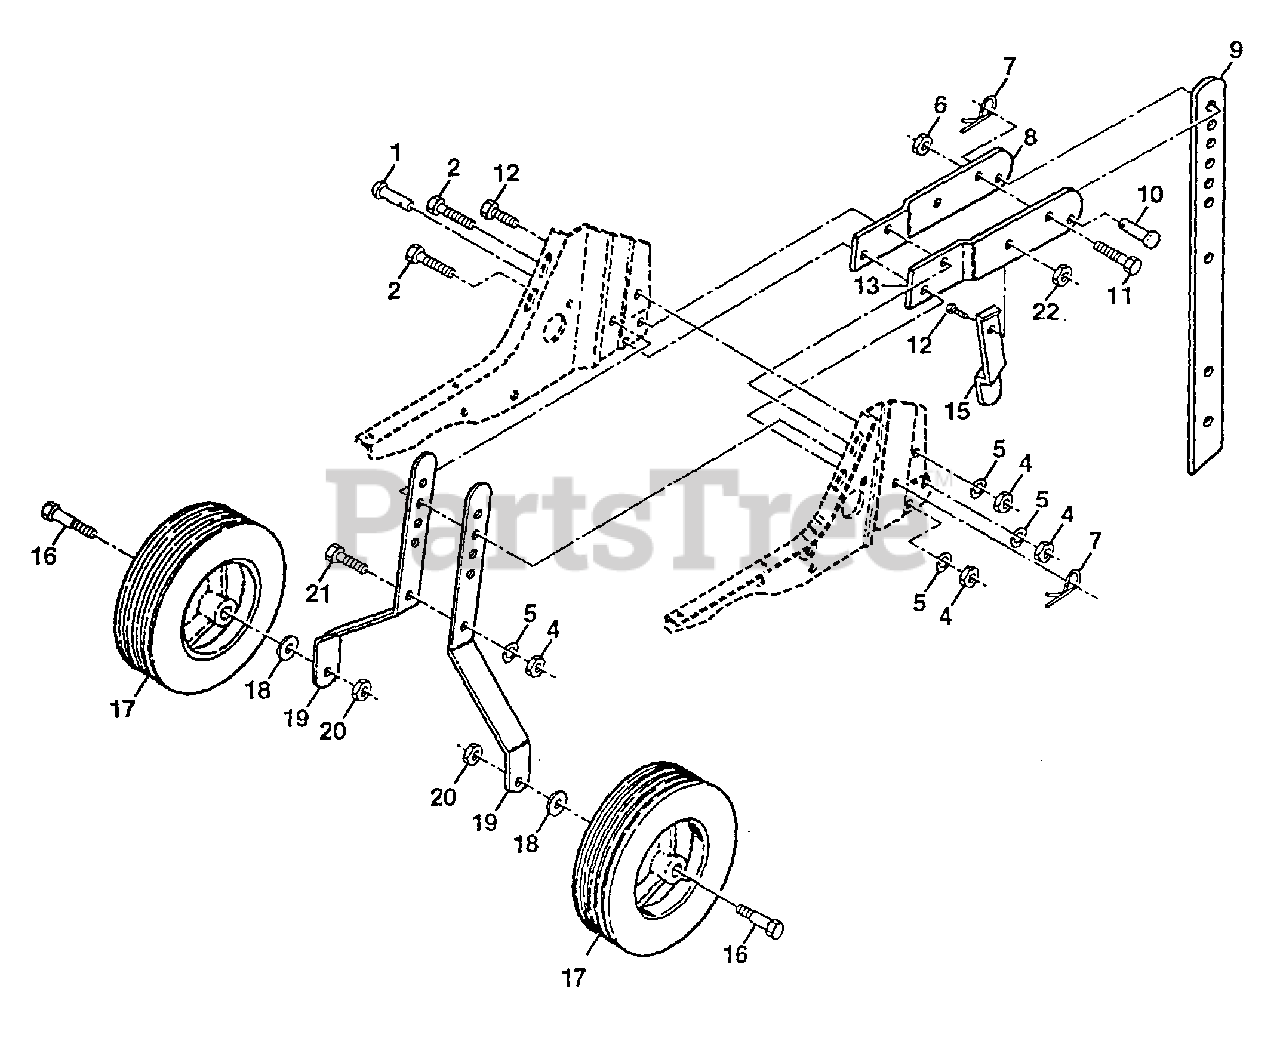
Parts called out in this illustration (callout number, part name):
1	Rivet Rd Hd Drilled 1 38
2	Bolt, Hex 5/16-18 x 1-1/4
4	Nut, Hex 5/16-18
5	Washer, Lock 5/16
6	Locknut, w/Insert 3/8-16
7	Clip, Hairpin
8	Support, Depth Stake, R.H.
9	Depth Stake
10	Pin, Clevis
11	Bolt Hex 5/16-18 x 1-1/2
12	Bolt, Hex 5/16-18 x 3/4
13	Support, Depth Stake, L.H.
15	Spring, Depth Stake
16	Bolt, Shoulder
17	Wheel
18	Washer 13/32 x 13/16 x 11 Ga.
19	Bracket, Wheel
20	Nut, Crownlock 3/8-16
21	Bolt Hex Hd 5/16-18 x 1
22	Locknut, w/insert 5/16-18
